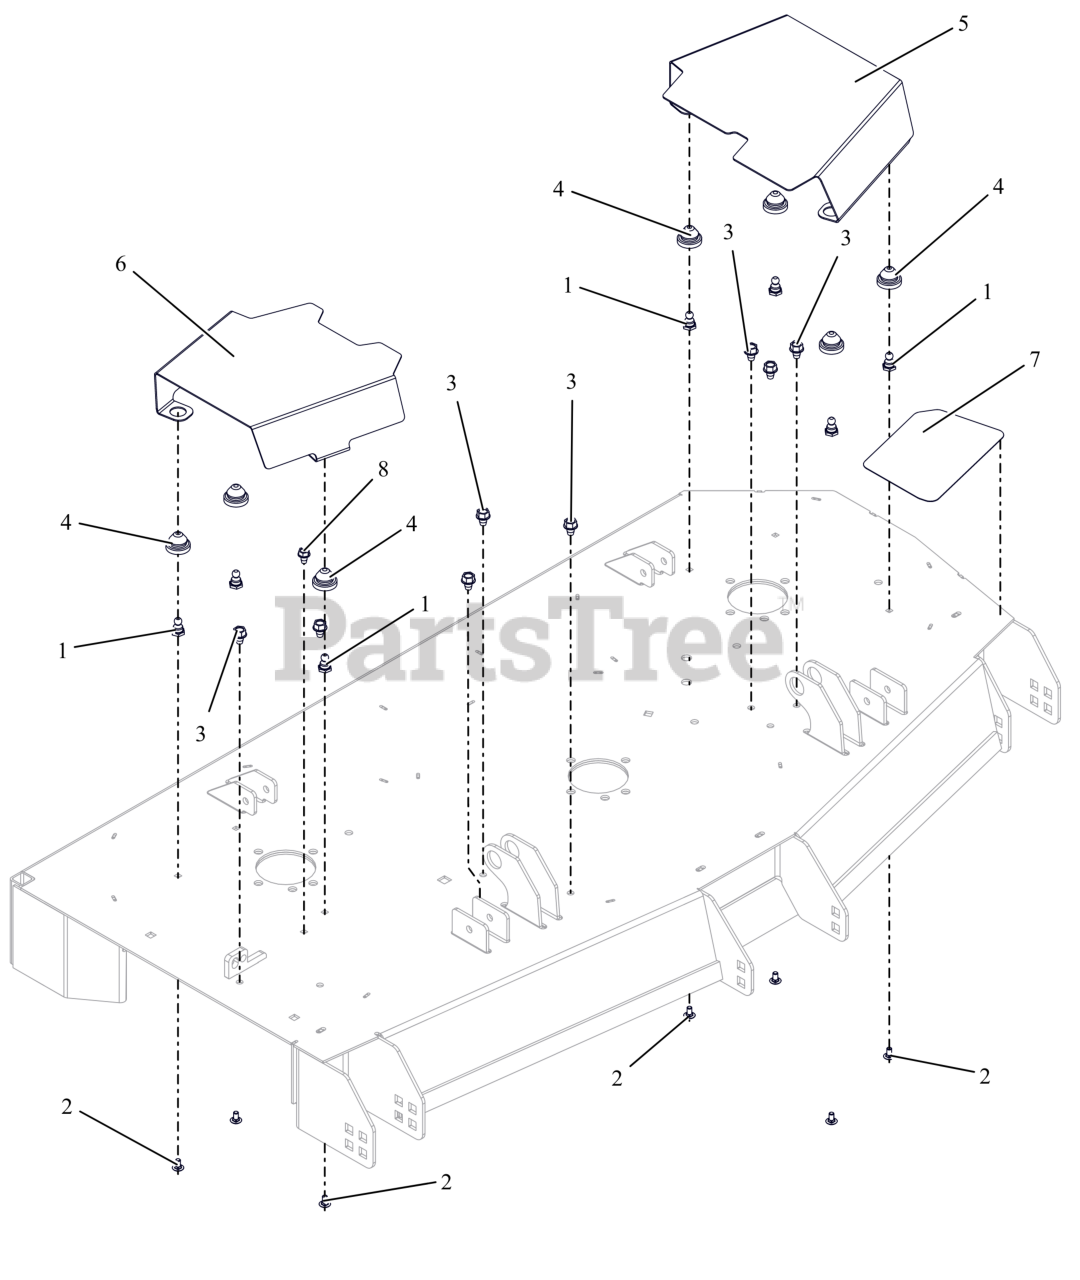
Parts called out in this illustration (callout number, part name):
1	STUD, BALL FEMALE .250-20 THREAD
2	BLT, RHSSN.25-20X.500 G5 ZCC
3	SCR,TAP .375-16X.50 HWH TR ZCC
4	COUPLING, RUBBER PUSH-IN
5	COVER- BELT 52" LEFT
6	COVER- BELT 52" RIGHT
7	GRIP, STEP ANTI SKID HD XF3
8	SCR,TAP .312-18X.50 HWH TR ZCC
